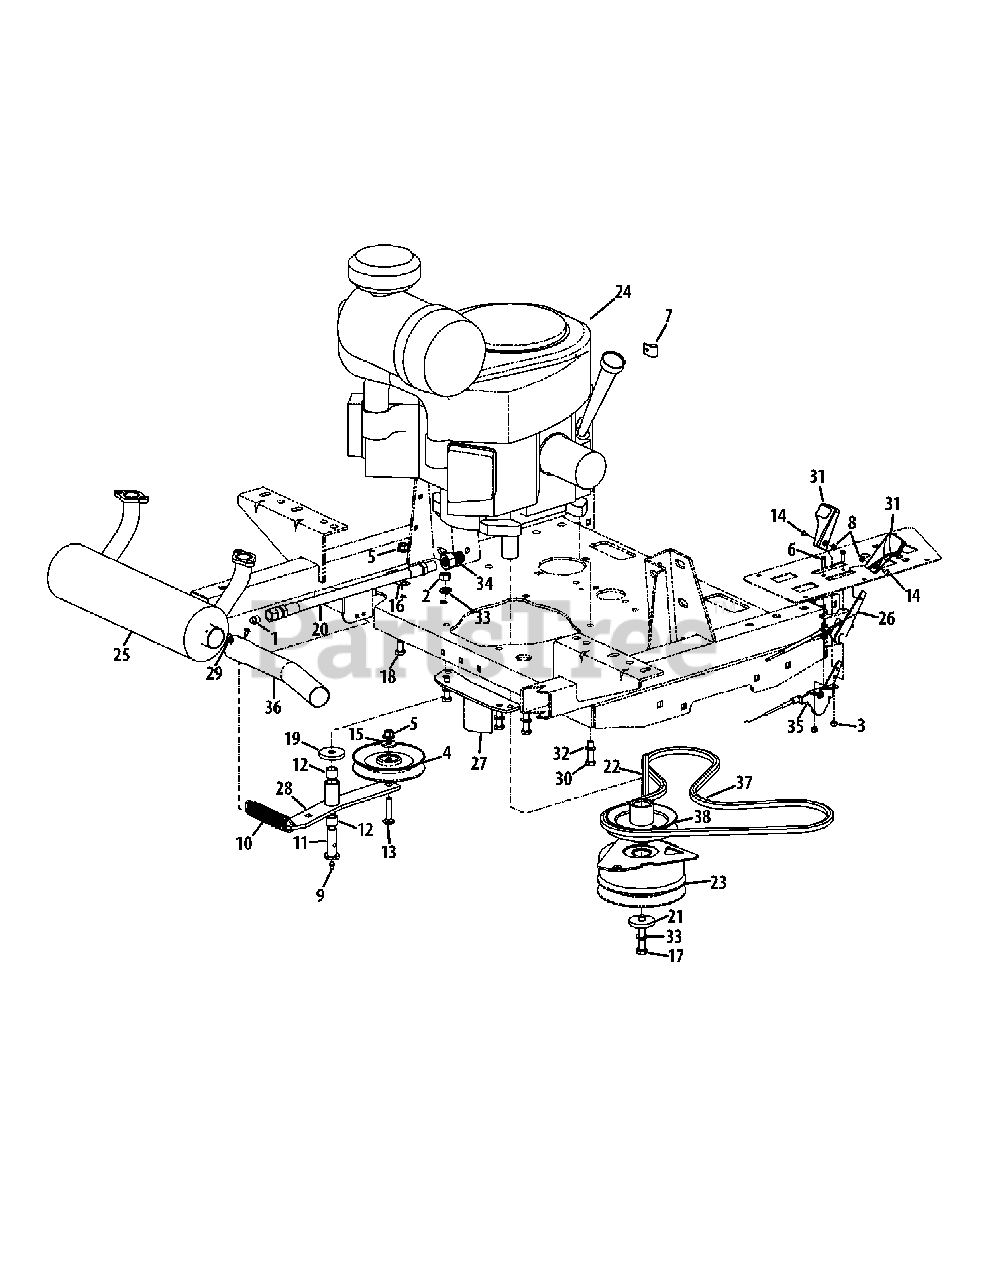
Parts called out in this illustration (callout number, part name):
1	Pipe Plug, 3/8
2	Nut, 7/16-14
3	Nut, #10-32
5	Flange Counter Lock Nut, 3/8-16
6	Machine Screw, #10-32 x .625
7	Clamp, 1/2
8	Nut, 8-32
9	Grease Fitting, 1/4-28
10	Extension Spring, 1.00 x 5.00 x .125
11	Shoulder Bolt, .625 x 1.95
12	Sleeve Bearing, .628 x.753 x .625
13	Carriage Bolt, 3/8-18 x 1.75
14	Machine Screw, #8-32 x .356
15	Washer, .406 x 1.00 x .105
16	Clip, .470 x 1.80
17	Hex Screw, 7/16-20 x 2.50
18	Hex Screw, 3/8-16 x .750
19	Washer, .438 x 1.75 x .250
20	Oil Drain Hose
21	Washer, .438 x 1.745 x .250
22	Key, .250 x .250 x 3.00
23	Brake Clutch
24	Kawasaki FX850V-AS11 Engine
26	Choke Cable
27	Clutch Return Assembly
28	Idler Arm Assembly
29	Hex Washer Screw, #10-16 x 0.500
30	Hex Screw, 3/8-16 x 1.50
31	Throttle Control Knob
32	Lock Washer, 3/8
33	Lock Washer, 7/16
34	Fitting, 1.0
35	Throttle Cable
36	Exhaust Pipe
38	Drive Pulley
